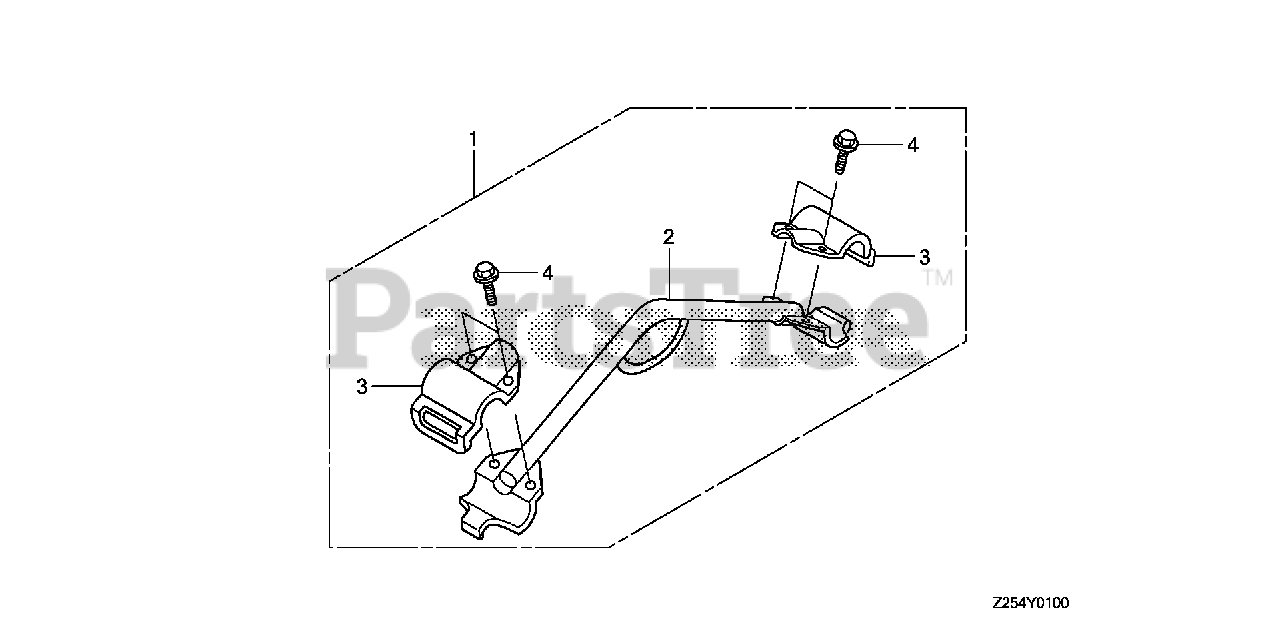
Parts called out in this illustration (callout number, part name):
1	HANGER KIT *NH105* (MAT BLACK)
2	HANGER *NH105* (MAT BLACK)
3	BRACKET, HANGER (UPPER)
4	BOLT, FLANGE (8X16)
